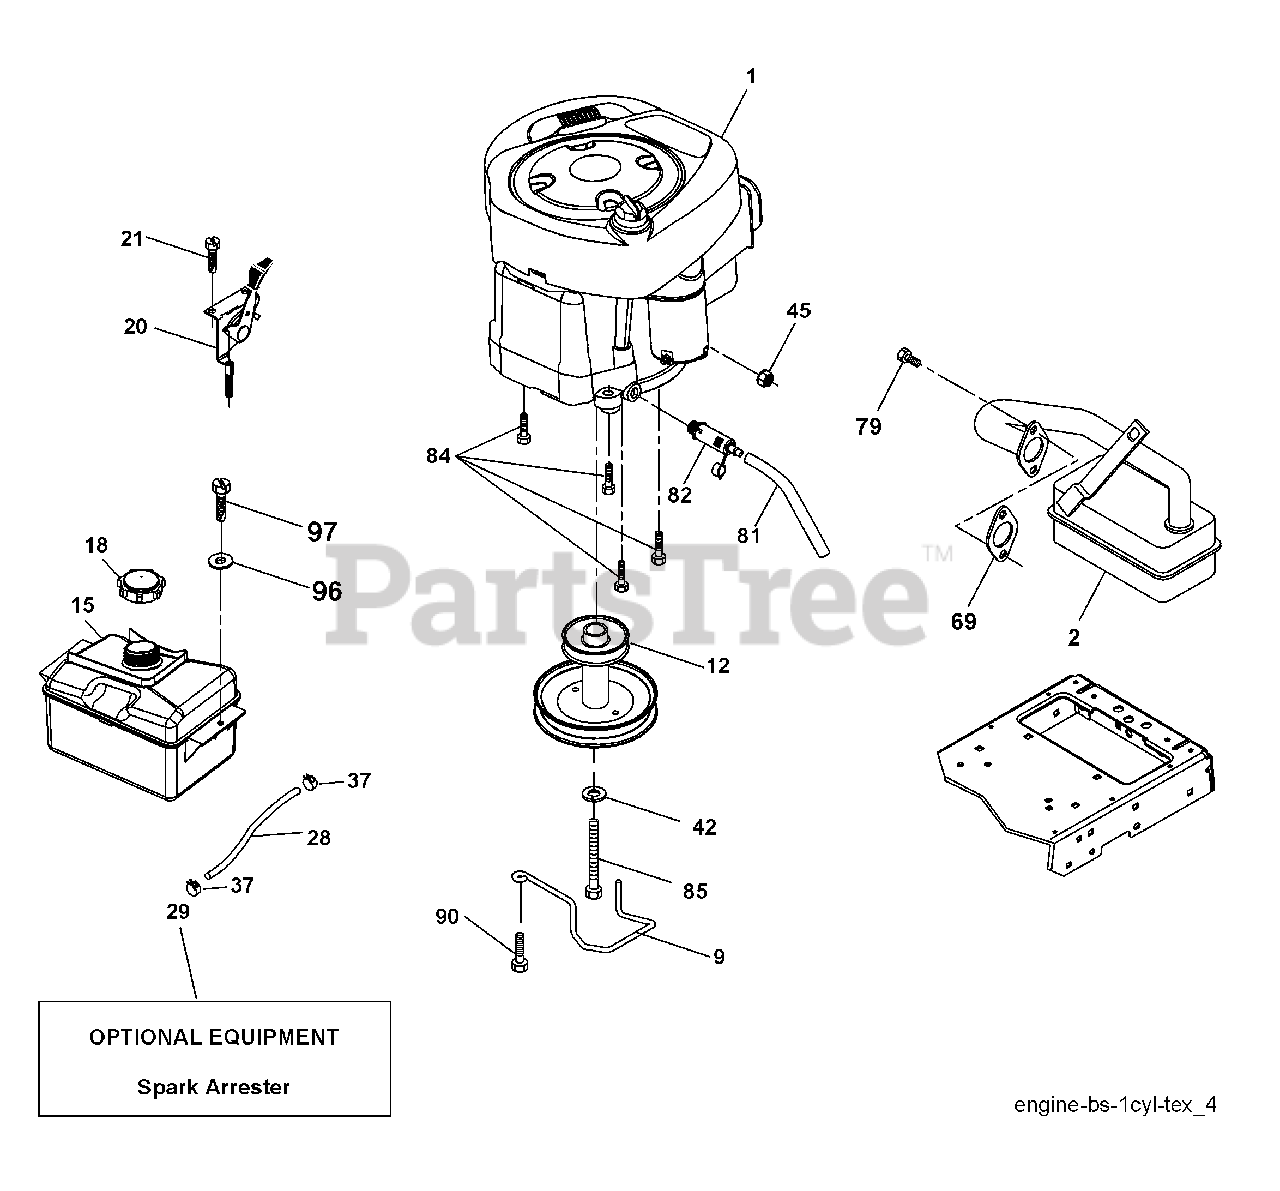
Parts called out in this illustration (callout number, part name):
9	Keeper Belt Engine
12	Pulley Engine
15	Tank Fuel
18	Cap Asm
20	Control Throttle
21	Screw 10 x 3/4 Single Lead-Hex
28	Fuel Line
29	Spark Arrester Kit
37	Clamp Hose
42	Washer Lock 7/16
45	Nut Keps Hex 1/4-20 unc
69	Gasket
79	Screw 5/16-18 x 3/4
81	Tube Drain Oil Easy
82	Plug Drain Oil
84	Screw 3/8-16 x 1/4
85	Bolt Hex 7/16-20 x 4 Gr. 5
90	Screw 3/8-16 x 1
96	Washer 9/32 x 7/8 x 16 Ga.
97	Screw 1/4-20 x 3/4
